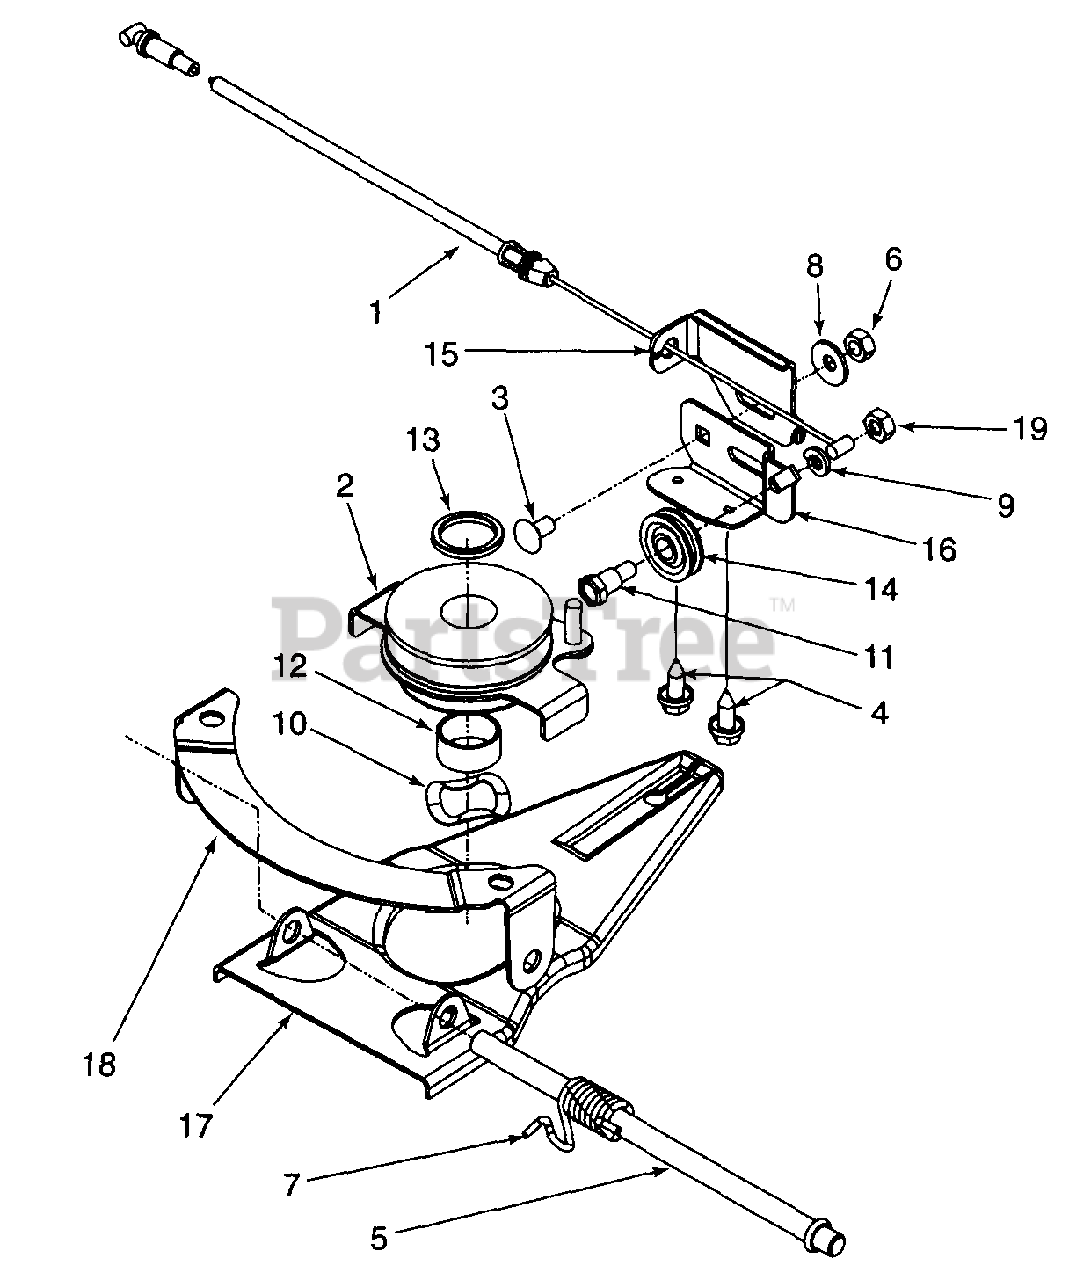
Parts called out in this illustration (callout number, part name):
1	6 Spd. Cable
2	Pulley Ass'y Mult-Spd.
3	Scr. 1/4-20 x .50 Carr.
4	Scr. AB 1/4-14 x .625 Hxinwsh
5	Pivot Shaft
6	Nut 1/4-20
7	Torsion Spring LH
8	Bell Wash. .265 x .75 x .062
9	Lock Wash. 1/4 Reg Duty
10	Wave Wash. 1.38 x .88 x .029
11	Shld. Scr. .375 x 1/4-14 AB
12	Slev Spcr. .88 ID 1.00 OD x .48
13	Slev Spcr .88 ID x 1.13 ID x .12
14	Roller Cable
15	6 Spd. Cable Adj. Bracket
16	6 Spd. Cable Mt. Bracket
19	Hex Nut 1/4-28
